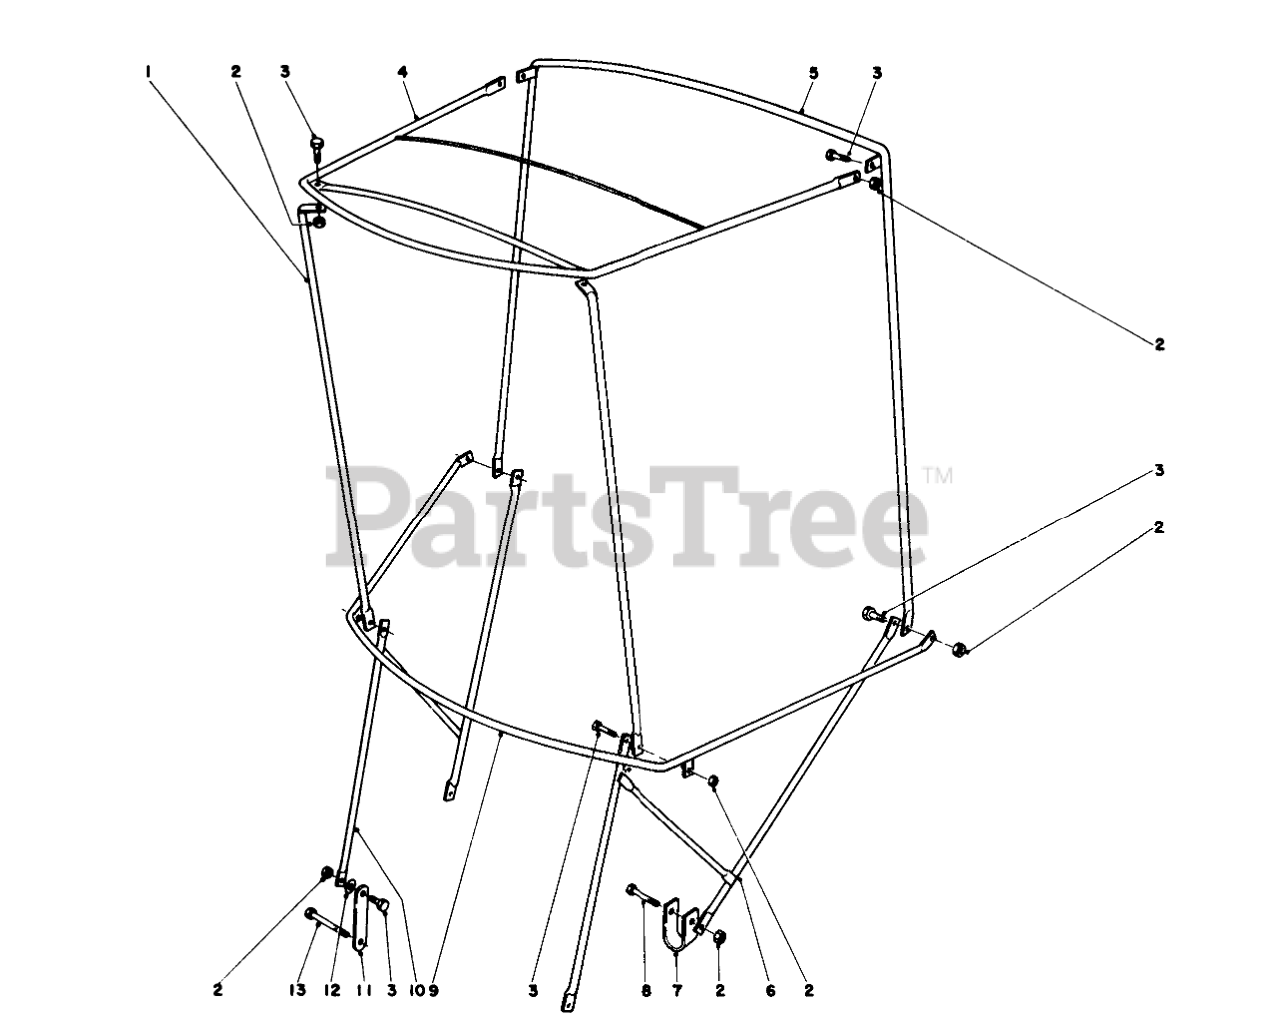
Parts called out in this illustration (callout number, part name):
2	NUT-LOCK
3	SCREW-HH
4	FRAME-TOP
5	BOW-VERTICAL, REAR
6	Attaching Bracket, L.H.
7	U CLAMP
8	SCREW-HH
9	BOW-CURVED
10	Attaching Bracket, R.H.
11	Mounting Strap
12	WASHER-LOCK/EXT
13	SCREW-HH
